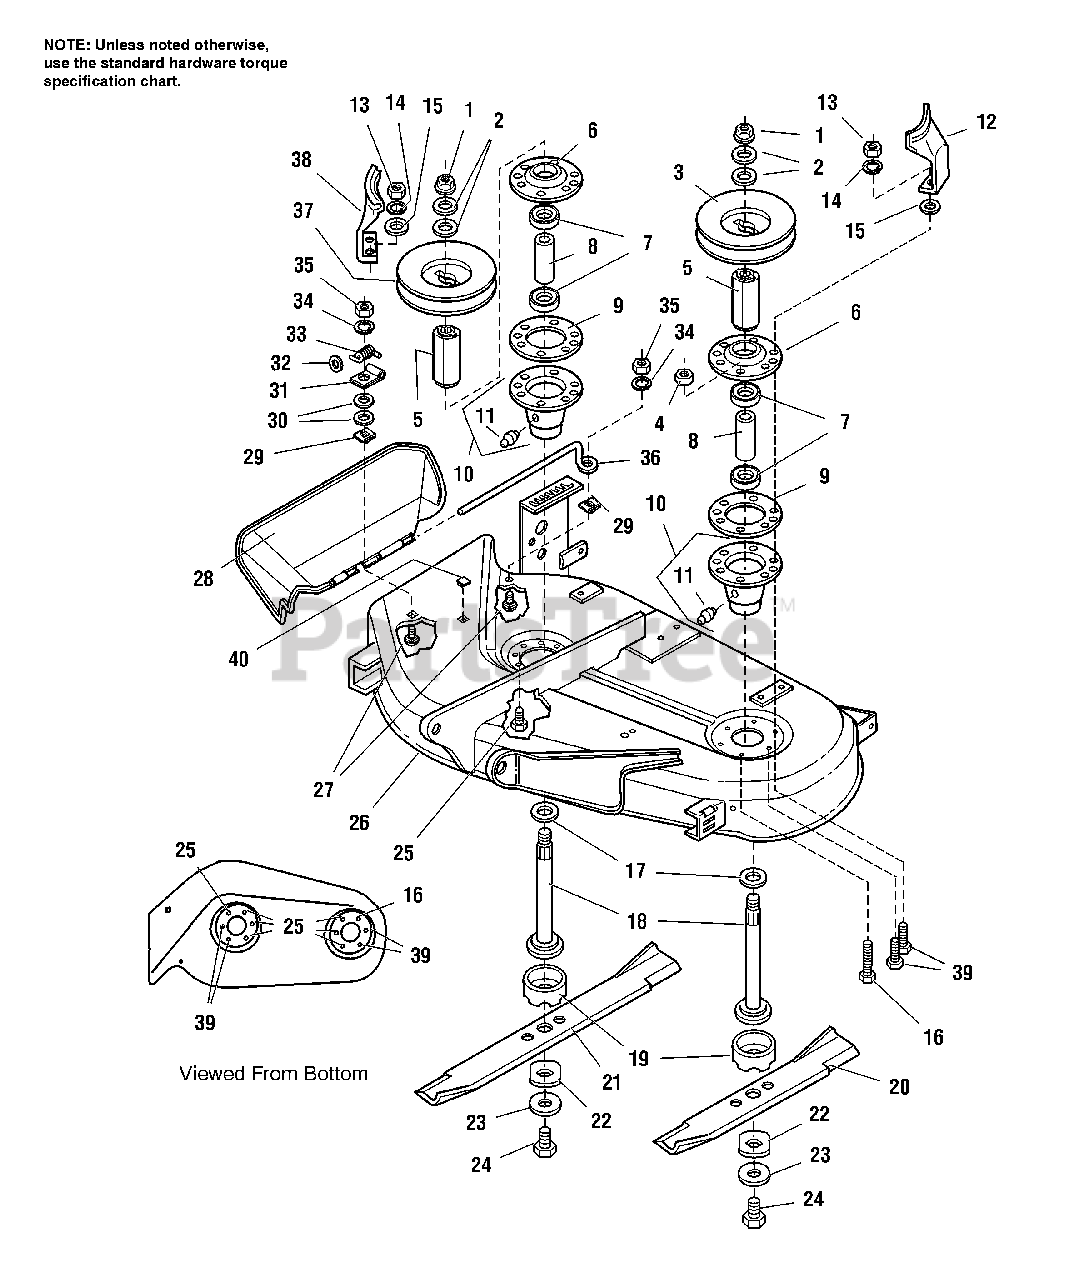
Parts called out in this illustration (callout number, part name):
1	NUT, Hex, Flange, 9/16-8
2	WASHER, Belleville
4	NUT, Hex, 5/16-18
6	COVER, Arbor Housing
9	GASKET, Foam
10	HOUSING ASSEMBLY, Arbor Bottom, w/Lube Fitting
11	FITTING, Grease
12	STOP, Belt, LH
13	NUT, Hex, Full, 5/16-18
14	LOCKWASHER, 5/16
15	WASHER, Flat, 3/8
16	CAPSCREW, Taptite Hex Washer Hd, 5/16-18 x 1-1/2
18	SHAFT, Arbor
19	SHIELD, Grass, Lower
20	BLADE, Mower, 16-1/8"
21	BLADE, Mower, 22-1/4"
22	WASHER, Hex
23	WASHER, Spring
24	CAPSCREW, Hex, Hd., 7/16-14 x 1/4
25	CAPSCREW, Taptite Hex Washer Hd, 5/16-18 x 3/4
26	MOWER DECK HOUSING, 38", Orange
26	MOWER DECK HOUSING, 38", Black
27	CARRIAGE BOLT, 1/4-20 x 7/8
28	DEFLECTOR, Plastic
29	NUT, Push On
30	WASHER, Plain, 1/4
32	WASHER, Plain, 5/16
34	LOCKWASHER, 1/4
35	NUT, Hex, 1/4-20, UNC
36	ROD, Deflector, Front
38	STOP, Belt, RH
39	CAPSCREW, Taptite Hex Washer Hd, 5/16-18 x 1
40	PLUG, Plastic
